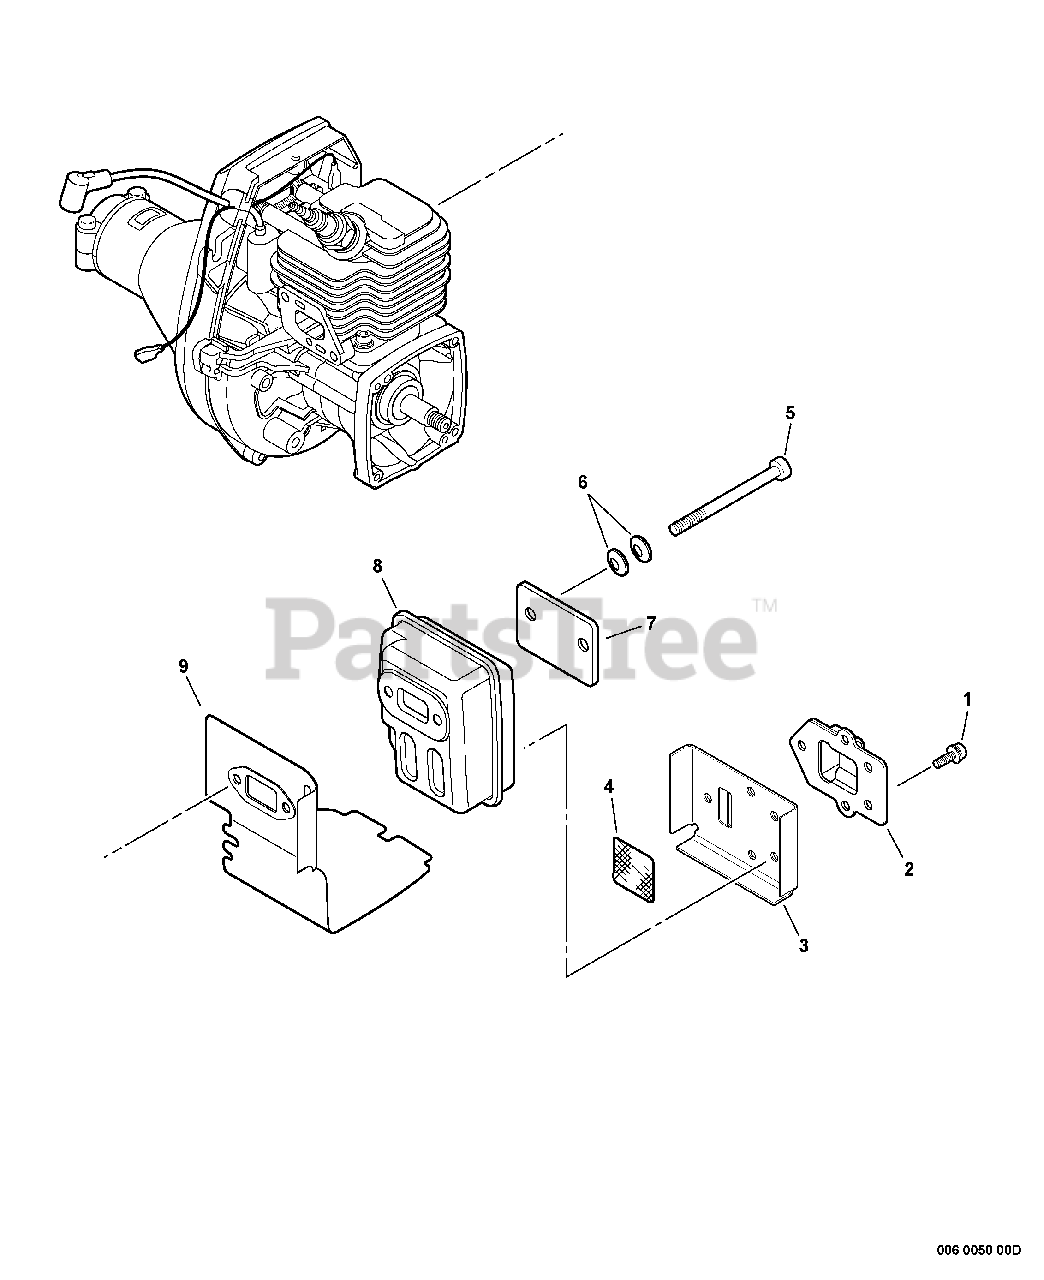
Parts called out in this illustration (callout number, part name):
1	SCREW 4×10
2	GUIDE, EXHAUST
3	GASKET, EXHAUST
4	SCREEN, SPARK ARRESTER
5	BOLT 5×55
6	CONICAL WASHER
7	PLATE, EYE
8	MUFFLER
9	SHIELD, EXHAUST
